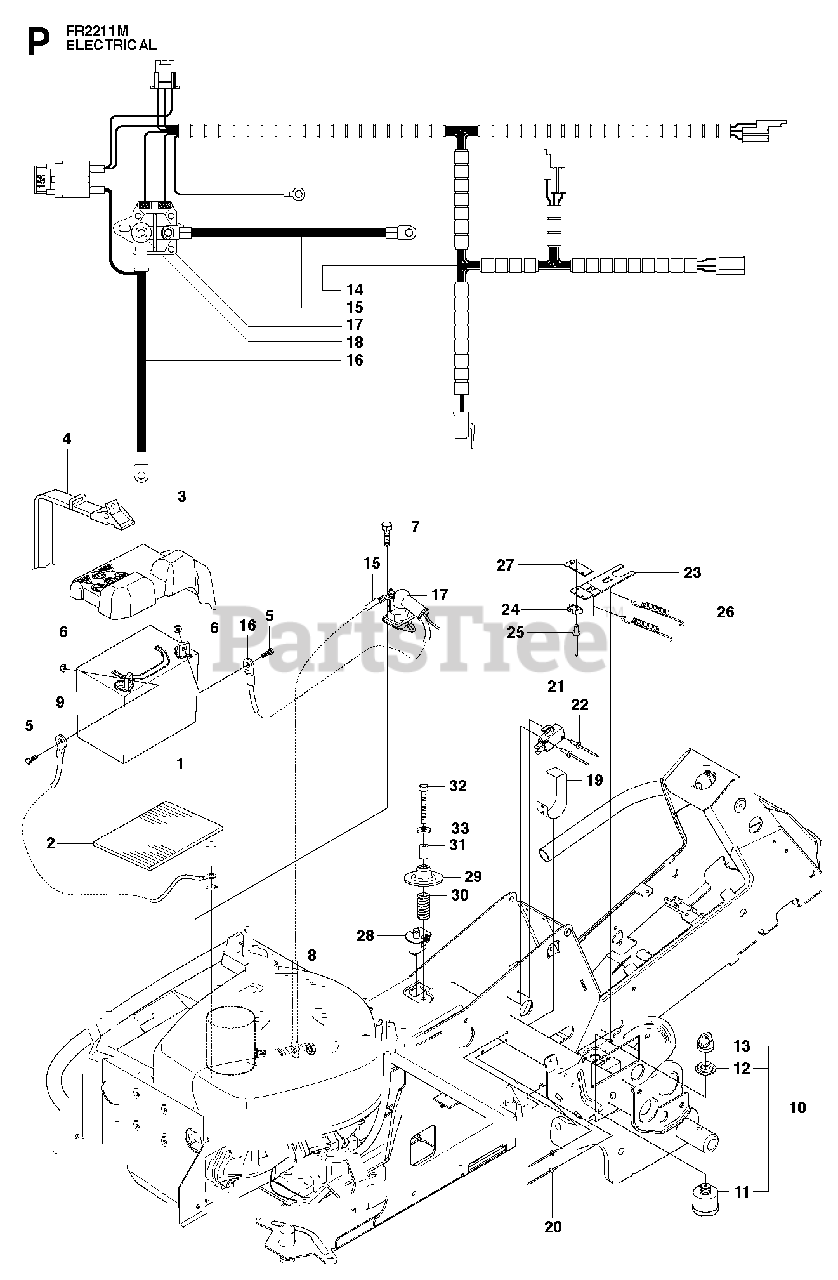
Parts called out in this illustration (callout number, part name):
5	SCREW EHHM
10	IGNITION SWITCH
11	IGNITION SWITCH
12	NUT
13	IGNITION KEY
21	%BRAKER
26	SPRING
31	SPACER TUBE
32	SCREW
33	WASHER BRB 8.4X17
